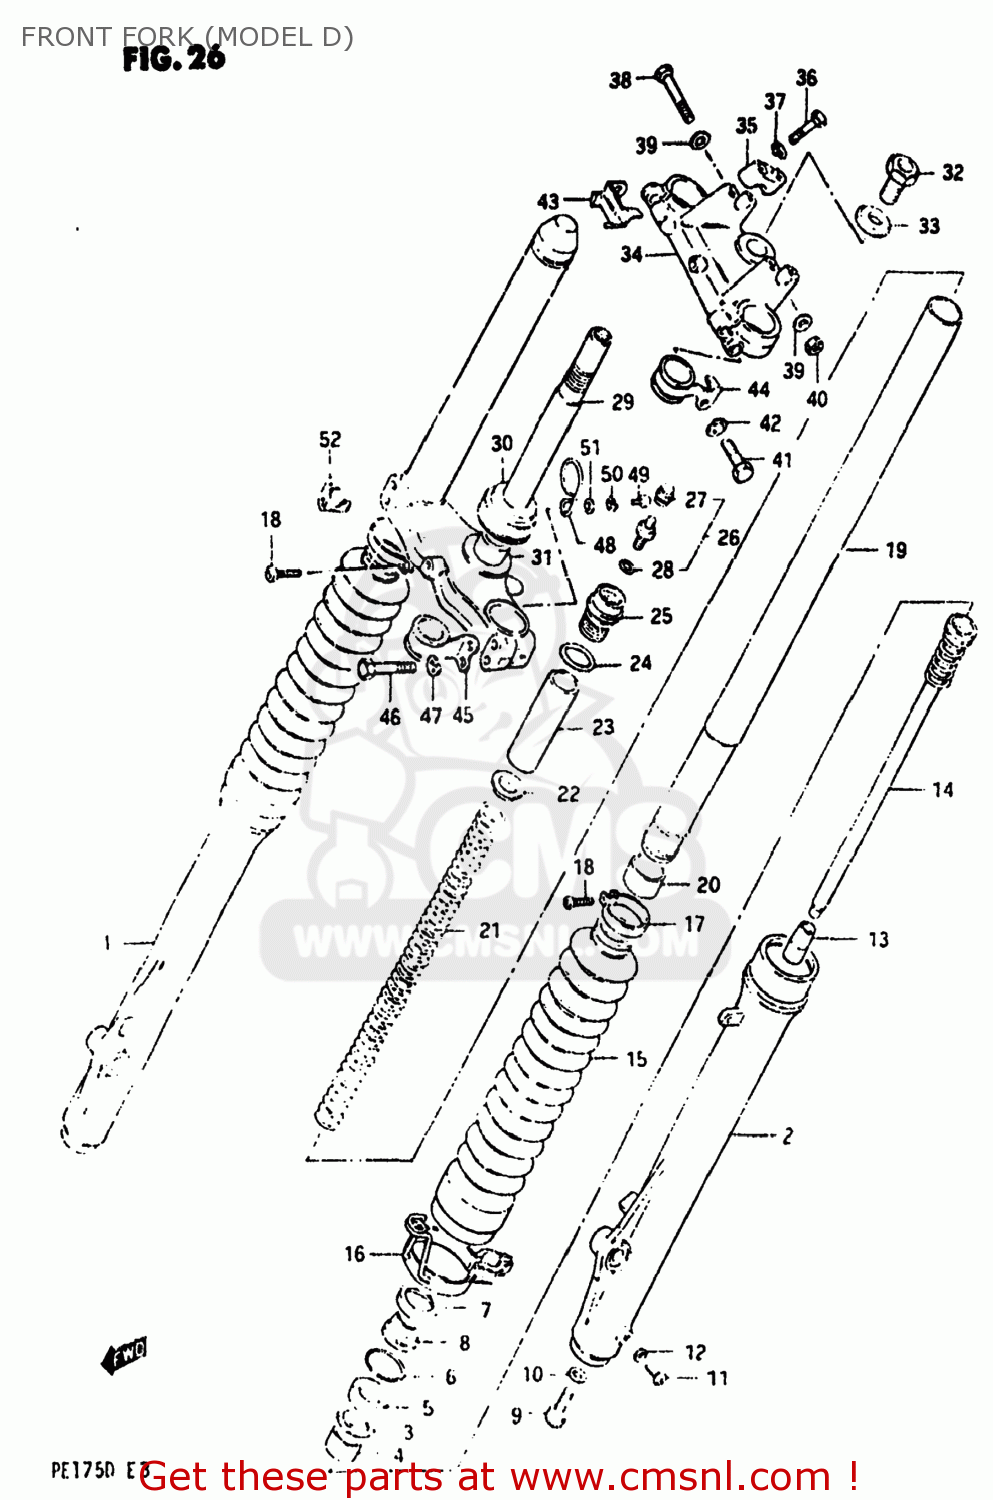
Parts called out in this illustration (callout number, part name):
0	DAMPER SET
1	TUBE,OUTER,RIGHT
2	TUBE,OUTER,LEFT
3	WASHER(40X50X2.3)
4	METAL,SLIDE
5	SEAL,OIL
6	RING,STOPPER
7	CASE,DUST SEAL
8	SEAL,DUST
9	BOLT,CYLINDER
10	GASKET,CYLINDER (NAS)
11	SCREW
12	GASKET,DRAIN,PLUG (NAS)
13	PIECE,OIL LOCK
14	CYLINDER,FRONT FORK
15	BOOT
16	BAND,FORK COVER BOOT
17	BAND,BOOT
18	SCREW 4X10
19	TUBE,FORK,INNER
20	PISTON
21	SPRING,FRONT FORK
22	GUIDE
23	SPACER,FRONT FORK SPRING
24	O RING
25	CAP,FORK INNER TUBE
26	VALVE,FRONT FORK AIR
27	CAP,VALVE
28	O-RING
29	STEM,STEERING
30	BEARING
31	WASHER,THRUST
32	BOLT
33	WASHER
34	HEAD,STEERING STEM
35	HOLDER,HANDLEBAR
36	BOLT
37	LOCK WASHER
38	BOLT 8X50
39	WASHER
40	NUT
41	BOLT
42	LOCK WASHER
43	BRACKET,TOOL FITTING,UPPER
44	GUIDE,CABLE
45	CLIP,CABLE
46	BOLT 8X45
47	LOCK WASHER
48	CLIP
49	SCREW
50	LOCK WASHER
51	WASHER
52	BRACKET,TOOL FITTING,LOWER
